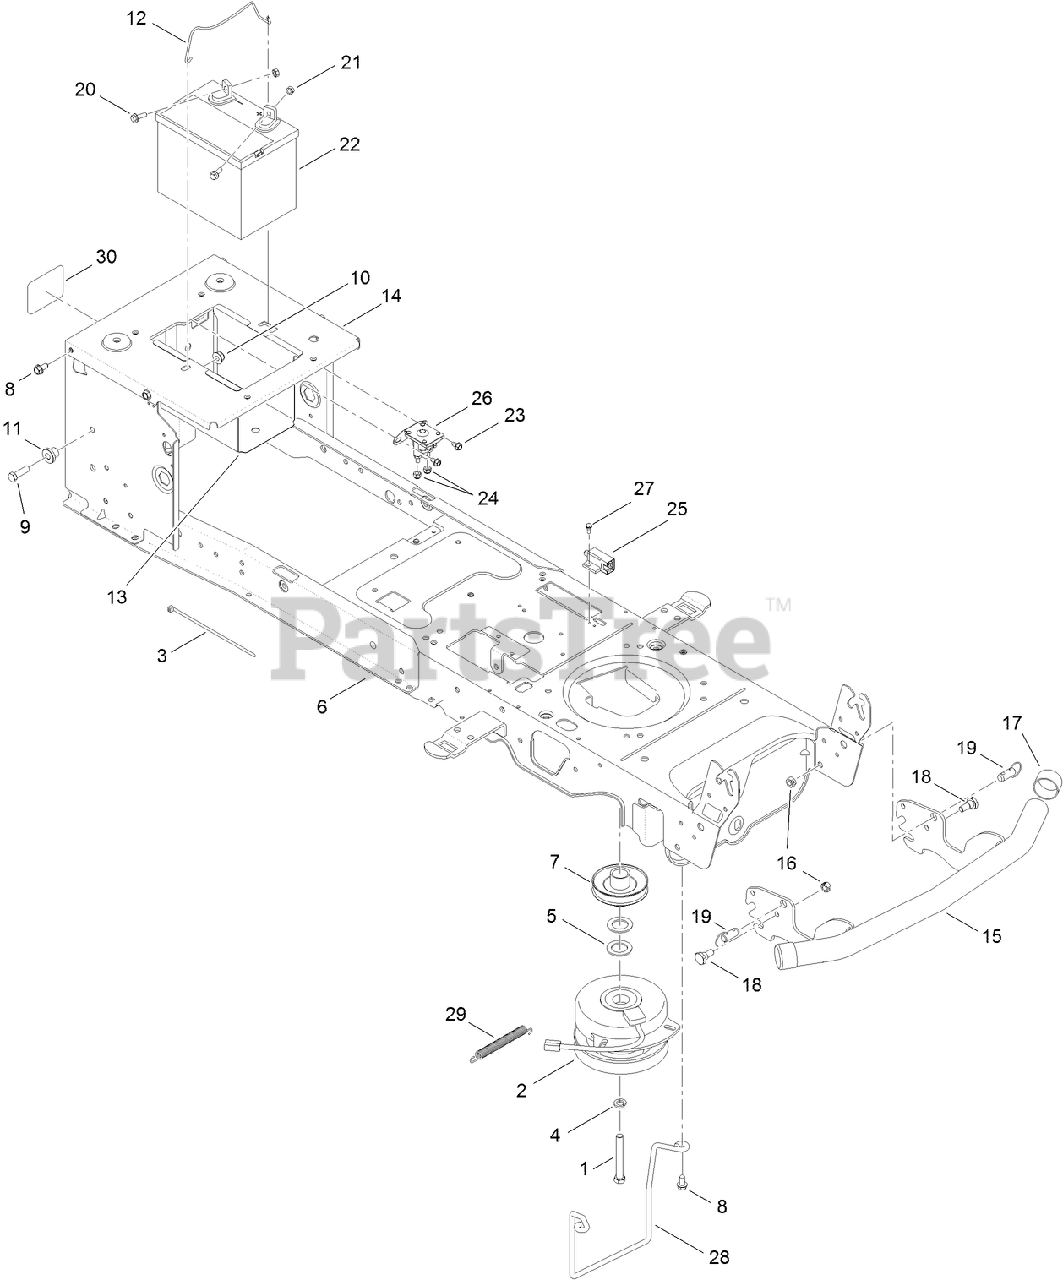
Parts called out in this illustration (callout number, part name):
1	SCREW-HH
2	CLUTCH-ELECTRIC
3	TIE-CABLE
4	WASHER-LOCK
5	WASHER-FLAT
6	LOWER FRAME ASM
7	PULLEY-ENGINE
8	SCREW-TAP
9	SCREW-HH
10	NUT-LOCK, FLANGE
11	SPACER-SHOULDER
12	ROD-HOLDDOWN, BATTERY
13	TRAY-BATTERY
14	BRACKET-FRAME, SEAT
15	BUMPER-UNIVERSAL
16	NUT-LOCK
17	CAP-HUB
18	BOLT-SHOULDER
19	PIN-RELEASE, QUICK
21	NUT-SEMS
22	BATTERY-245, CCA,DRY (FLAT TOP)
23	SCREW-TAP
24	NUT-LOCK, FLANGE
25	SWITCH-INTERLOCK, NO/NC
26	SOLENOID-12V, 2 POST 2 TAB
27	BOLT-SHOULDER
28	ROD-KEEPER, BELT
29	SPRING-EXTENSION
30	DECAL-RELEASE, HYDRO
